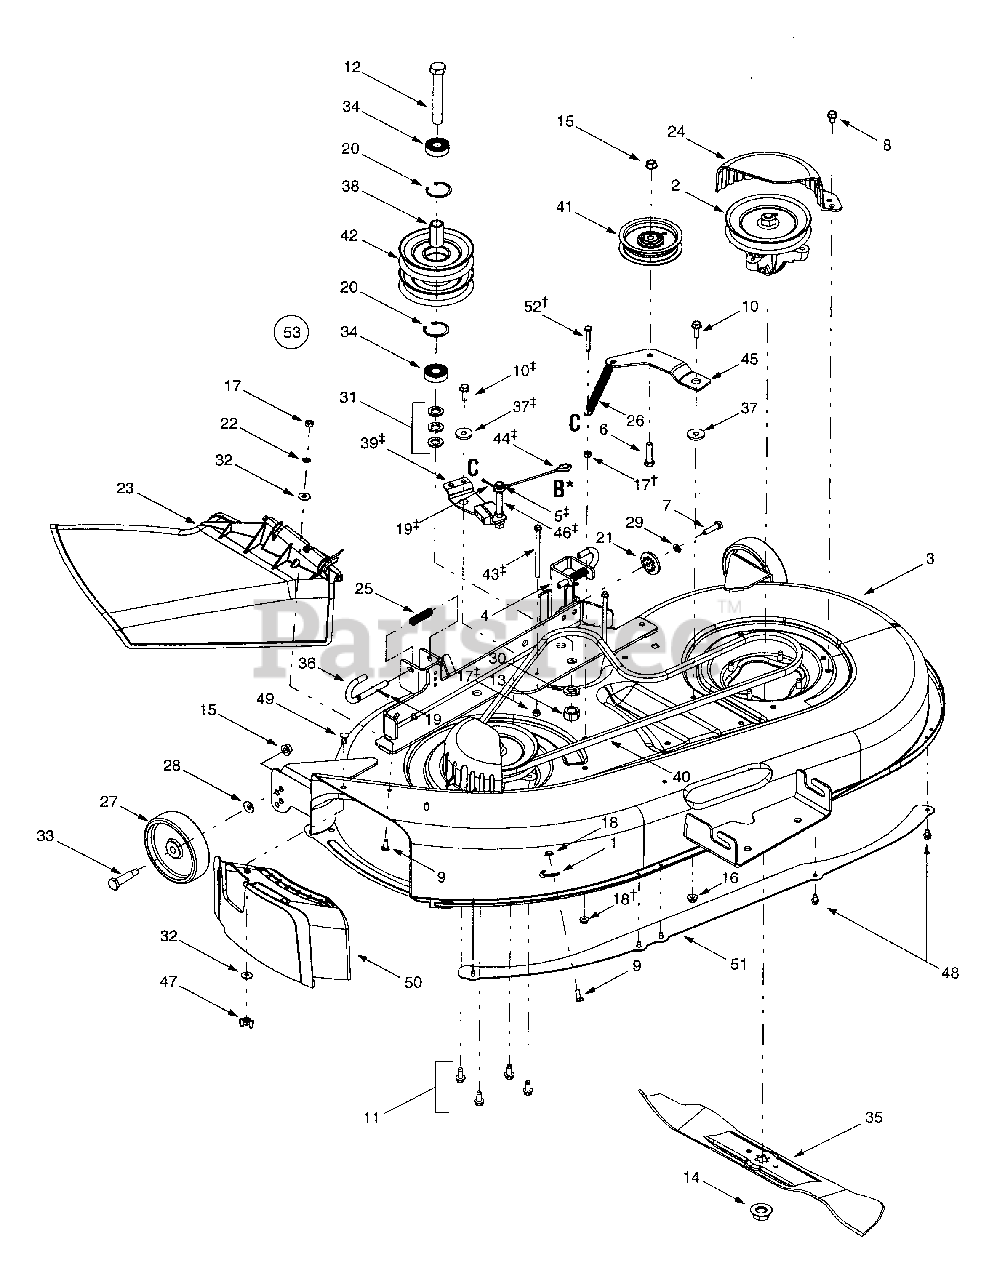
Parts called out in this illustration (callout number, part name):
1	Retainer Hook
2	Spindle Assembly, 5.75 Dia.
5	Flat Washer, .385 x .62 x .063
6	Hex Cap Screw, 1/4-20 x 1.5
7	Hex Cap Screw, 5/16-18 x 1.25
8	Self-tapping Screw, 5/16-18 x .625
9	Hex Cap Screw, 1/4-20 x .62
10	Hex Head Washer Screw, 5/16-18 x .875
11	Self-tapping Screw, 5/16-18 x .75
12	Hex Cap Screw, 5/8-18 x .875
13	Hex Nut, 5/8-18
14	Hex Flange Nut, 5/8-18
15	Flange Lock Nut, 3/8-16
16	Flange Lock Nut, 5/16-18
17	Hex Nut, 1/4-20
18	Hex Flange Lock Nut, 1/4-20
19	Cotter Pin, 1/8 x 1.25
20	Internal Snap Ring
21	Deck Adjustment Gear
22	Push Nut. .25 x.5
23	Side Discharge Chute Assembly
24	Belt Cover
25	Compression Spring, .406 x .531 x 1.75
26	Extension Spring, .50 x 4.74
27	Deck Wheel, 5 x 1.38
28	Bell Washer, .401 x .87 x .063
29	Lock Washer, 5/16
30	Lock Washer, 5/8
31	Flat Washer, .64 x 1.0 x .12
32	Bell Washer, .265 x .75 x .062
33	Shoulder Screw, .498 x 1.53
34	Bearing, .625 x 1.574 x .470
35	Three-in-one Blade, Star Center, 21.23"
36	Deck Release Pin
37	Shoulder Spacer, .625 x .324
38	Spacer, .635 x .88 x 1.72
39	Deck Brake Assembly
40	Deck Belt
41	Idler Pulley, 3.5
42	Double Pulley, 5.0
43	Self-tapping Screw, 1/4-20 x 4.0
44	Brake Cable, 5.05
46	Pin, 3/8-16, 3/8 x 3.27
47	Wing Nut, 1/4-20
48	Self-tapping Screw, 1/4-20 x .5
49	Carriage Screw, , 1/4-20 x .62
50	Mulch Plug
52	Hex Cap Screw, 1/4-20 x 1.75
